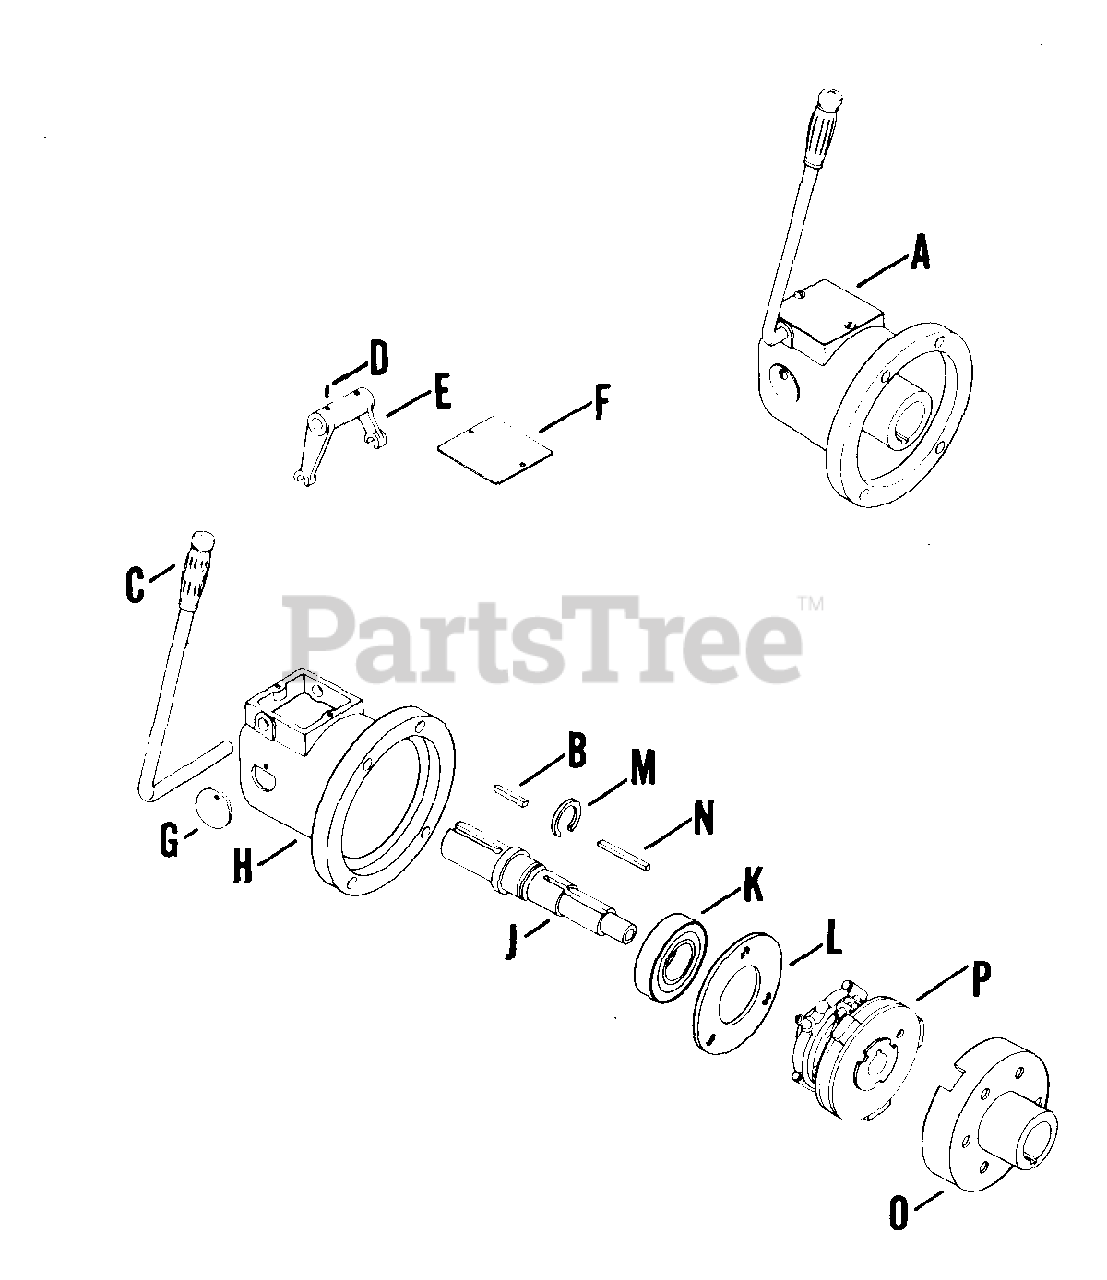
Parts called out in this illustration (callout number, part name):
F	PLATE - DISCONTINUED
K	Bearing
N	KEY - (#DSC)
O	CUP - DISCONTINUED
